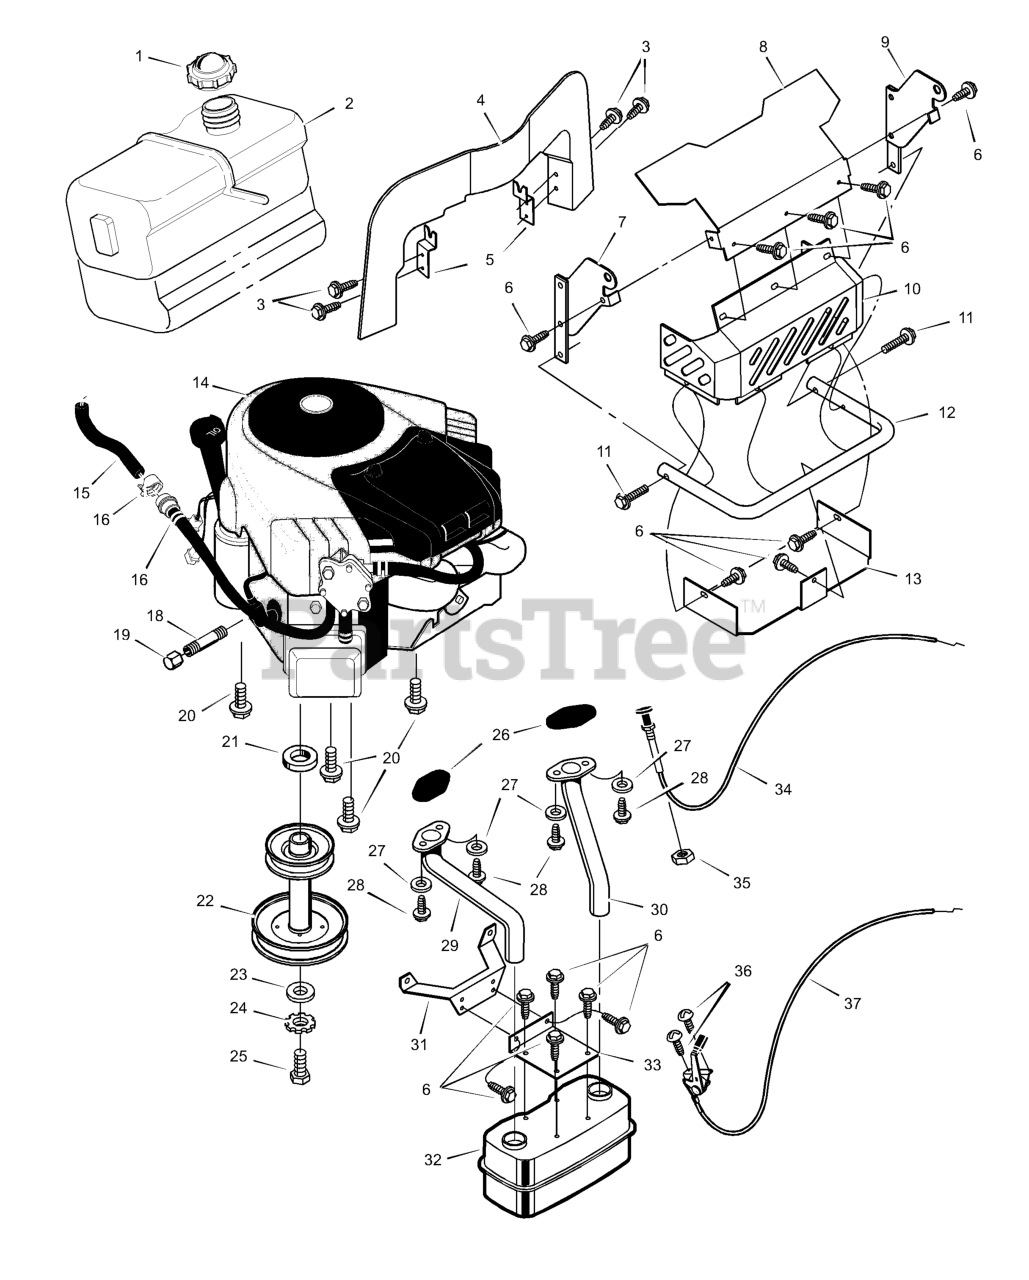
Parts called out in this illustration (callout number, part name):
1	Cap, Fuel
2	Tank, Fuel
3	Screw
4	Baffle
5	Clip, Baffle Mounting
7	Assembly, Right Grille Support
8	Shield, Heat
9	Assembly, Left Grille Support
10	Shield, Heat
13	Shield, Lower
14	Engine *
15	Line, Fuel (17 inches long)
16	Clamp
18	Pipe, Oil Drain
19	Cap, Oil Drain
20	Bolt
22	Pulley, Stack
24	Lockwasher
27	Washer
28	Bolt
29	Tube, Right Exhaust
30	Tube, Left Exhaust
31	Bracket, Muffler Mount
32	Muffler
33	Bracket, Muffler
35	Nut
37	Control, Throttle
